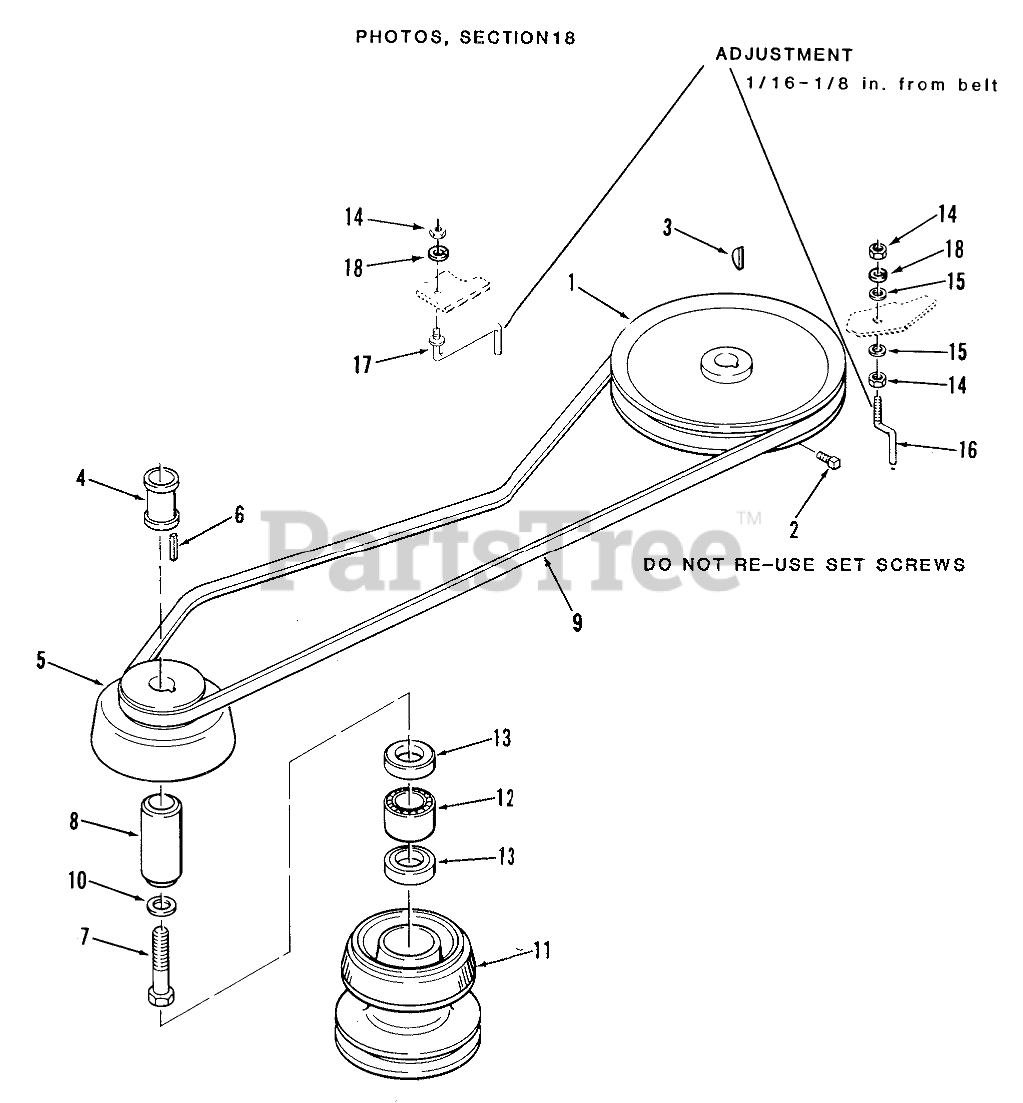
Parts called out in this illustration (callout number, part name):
2	Set Screw
3	KEY-HI-PRO
4	TUBE SPACER
5	PULLEY-ENGINE
7	HEX HD CAP SCREW
8	RACE BEARING
9	V-BELT
10	WASHER
11	Assy Pulley Mwr Dr
12	BRG-NEEDLE OPEN END
13	SEAL-OIL
14	Nut
15	WASHER 5/16 SAE
16	GUIDE-BELT
17	GUIDE-BELT
18	Lockwasher
